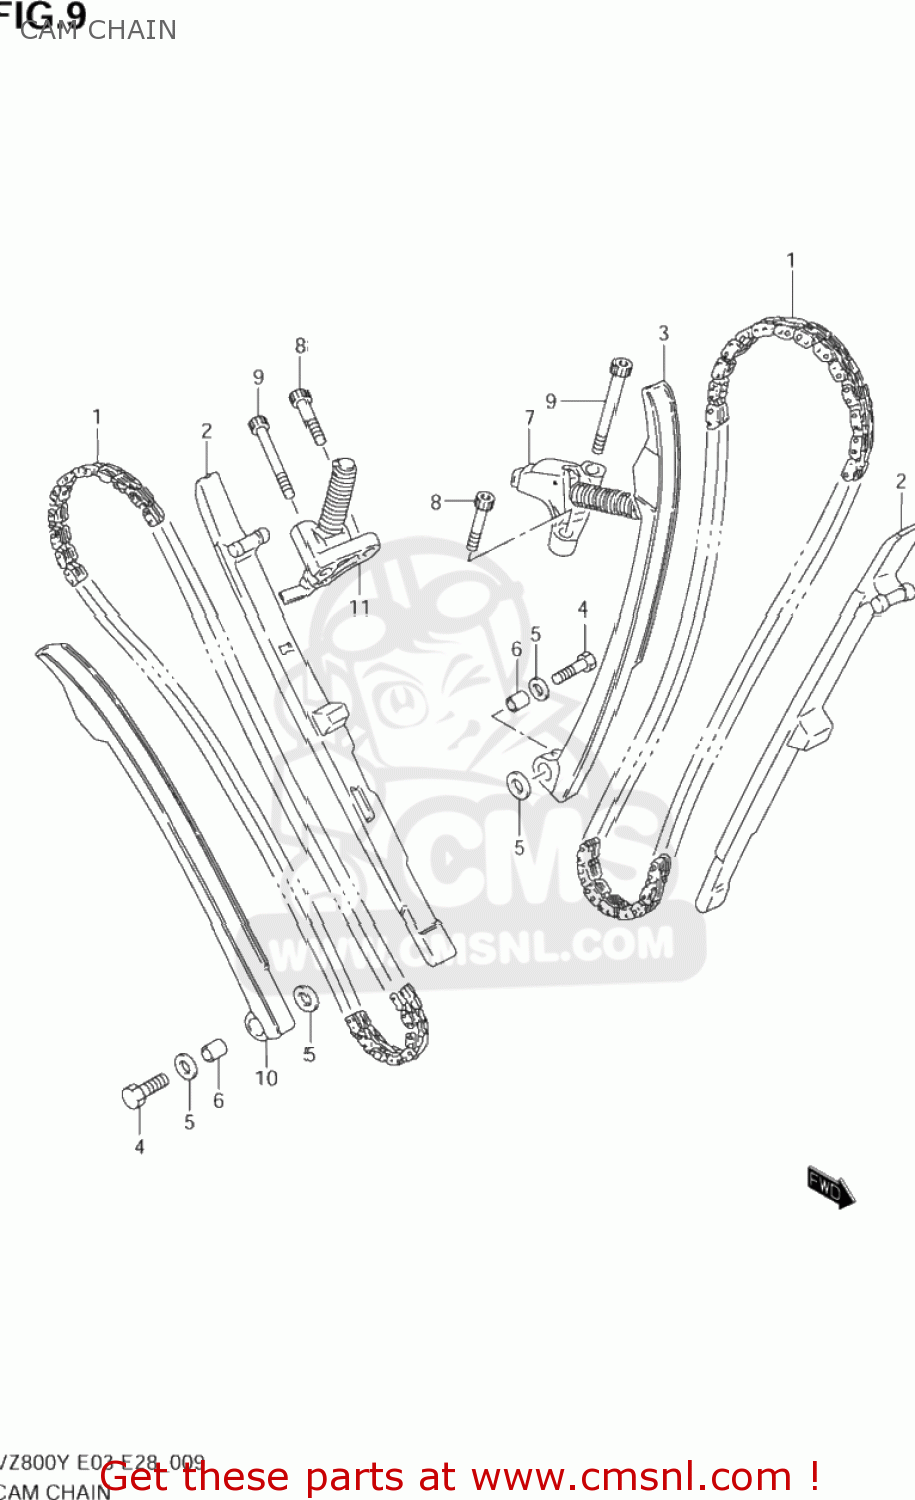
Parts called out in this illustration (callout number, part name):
1	CHAIN,CAMSHAFT DRIVE
2	GUIDE,CAM CHAIN
3	TENSIONER,FR CAM CHAIN
4	BOLT(6X26)
5	WASHER
6	SPACER(6X11X11)
7	ADJUSTER ASSEMBLY,FRONT TENSIONER
8	BOLT,CRKCASE,R
9	BOLT
10	TENSIONER,RR CAM CHAIN
11	ADJUSTER ASSEMBLY,REAR TENSIONER
